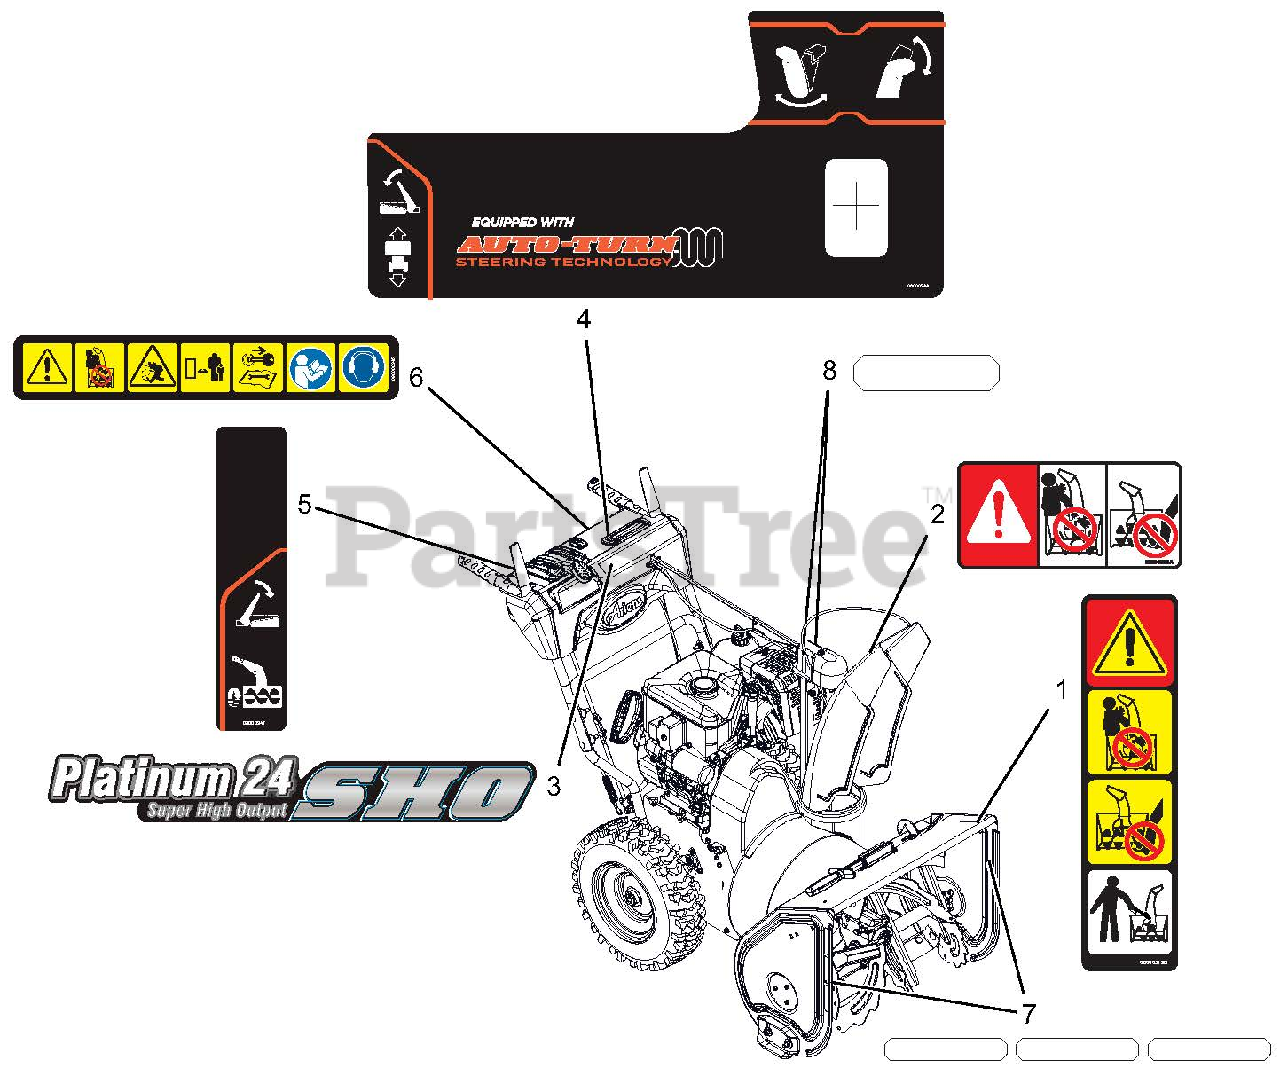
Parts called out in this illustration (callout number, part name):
1	DECAL, DANGER - ROTATING PARTS
2	DECAL, DANGER
3	DECAL,DASH-PLATINUM 24 SHO
4	DECAL,CONTROL-LG QT2
5	DECAL,CONTROL-RH CONTROL
6	DECAL,DASH - SAFETY
7	DECAL,REFLECTIVE,HOUSING
8	DECAL,REFLECTIVE,GEAR COVER
